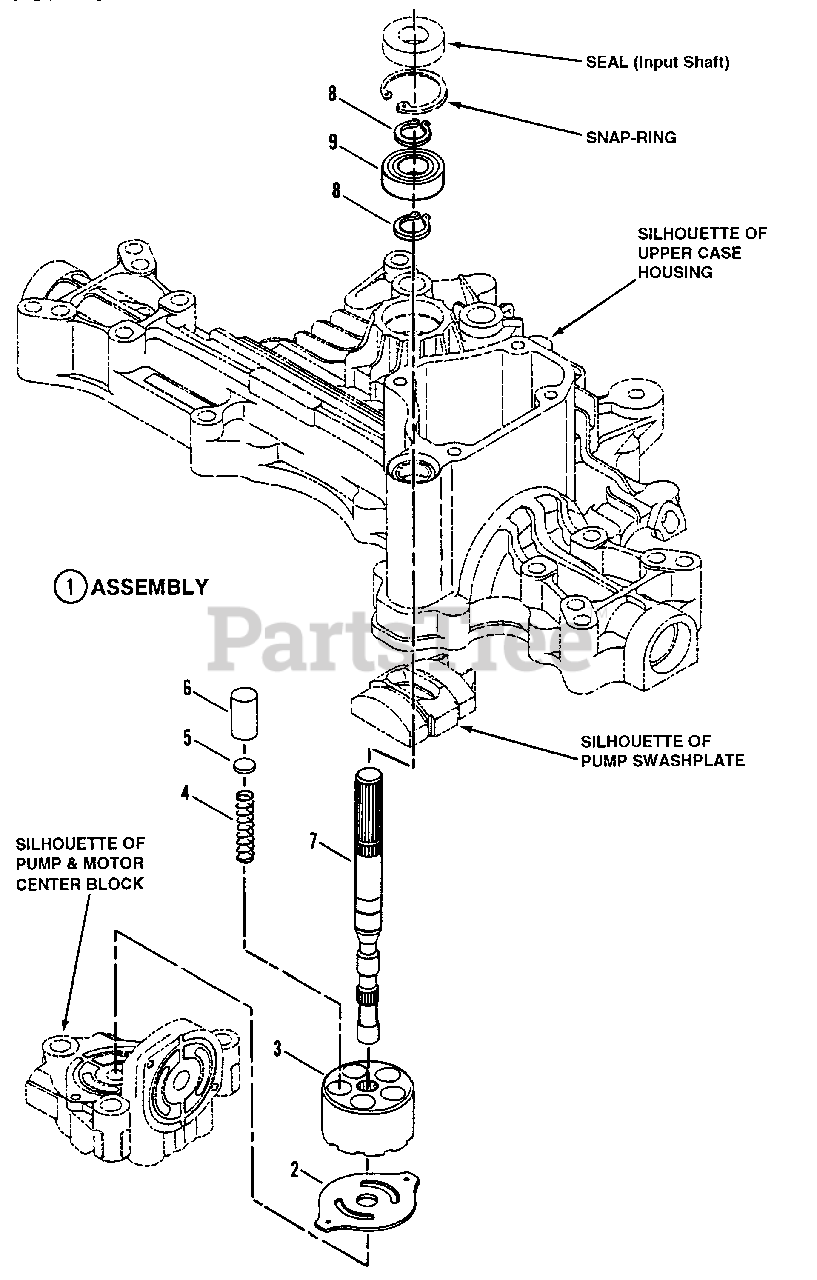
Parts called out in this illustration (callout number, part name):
1	ASSEMBLY, Cylinder Block
3	CYLINDER BLOCK, Pump
4	SPRING, Piston
5	WASHER, Pump Piston
6	PISTON, Cylinder Block
7	SHAFT, Pump Input
8	SNAP-RING
9	BEARING, Ball
